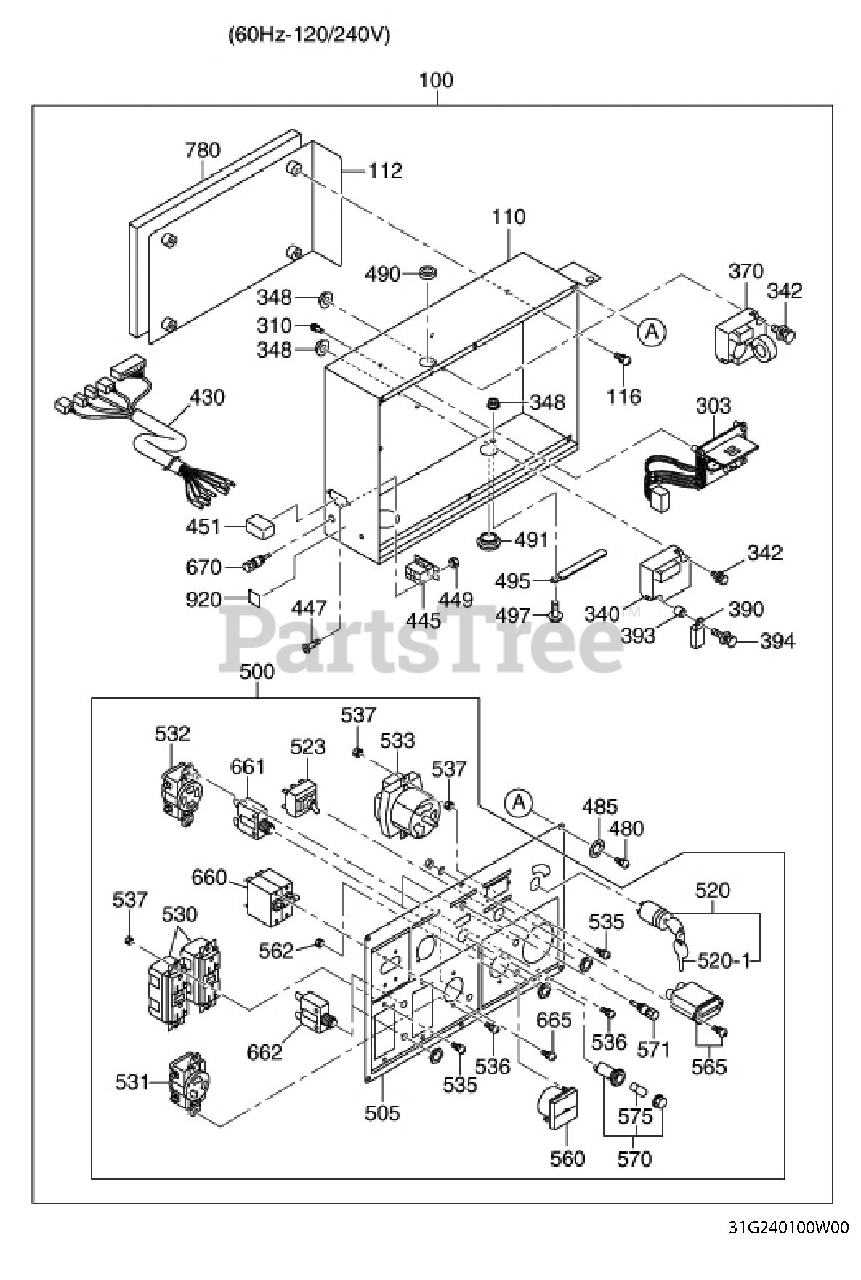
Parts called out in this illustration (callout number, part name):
100	CONTROL BOX AY
110	CONTROL BOX UNIT
116	SCREW and WASHER ASSY
310	SCREW
340	ECU(O/S & R/C) CP
342	SCREW and WASHER ASSY
348	FLANGE NUT
370	IDLE CONTROL UN CP
393	SPACER
394	SCREW
480	SCREW and WASHER ASSY
490	GROMMET
495	CLAMP
497	FLANGE BOLT
500	CONTROL PANEL AY
505	CONTROL PANEL
520	KEY SWITCH
523	AUTO IDLE SWITCH
530	AC CONSENT (GFCI)
531	AC RECEPTACLE
532	AC RECEPTACLE
533	AC RECEPTACLE
535	SCREW and WASHER ASSY
536	SCREW and WASHER AY
560	VOLTMETER
565	HOUR METER
570	PILOT LAMP
575	LAMP
660	BREAKER
665	SCREW and WASHER ASSY
